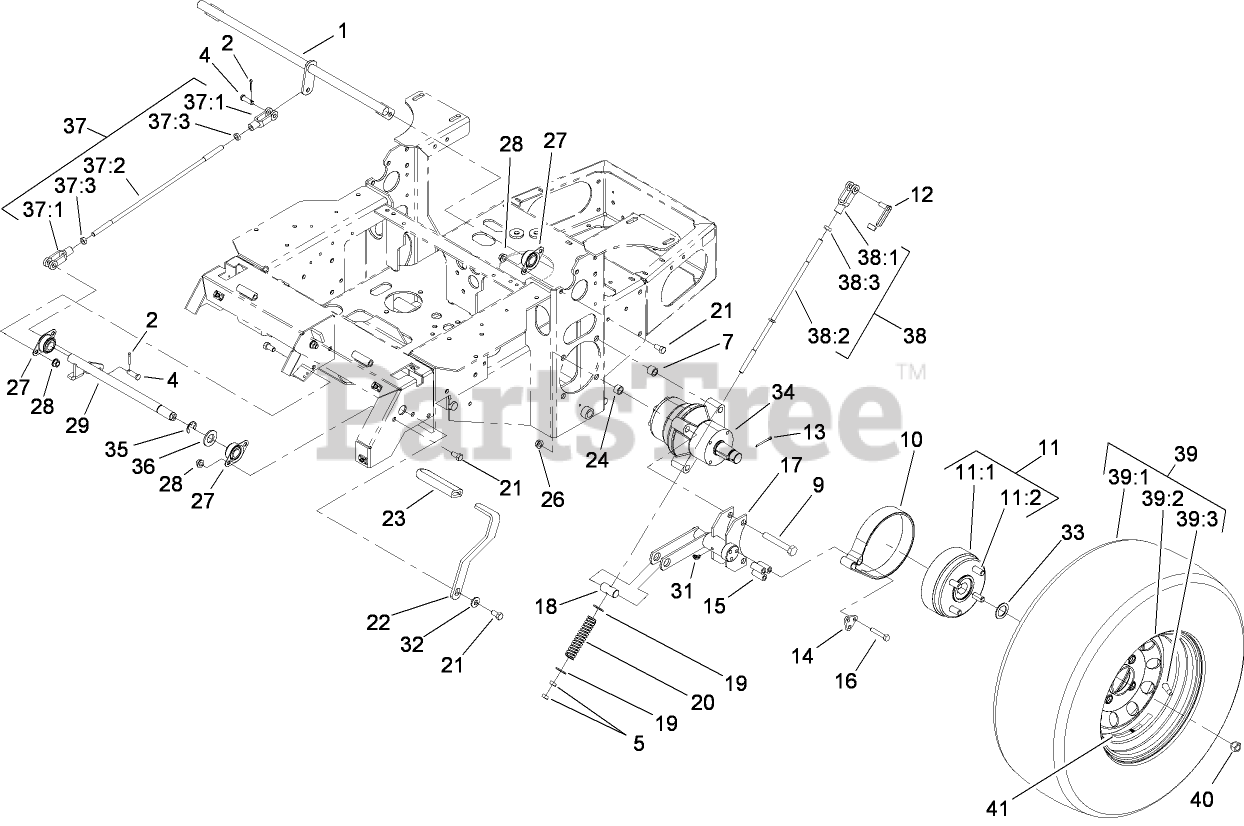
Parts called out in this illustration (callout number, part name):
1	CRANK-BRAKE, PARK
2	PIN-COTTER
4	PIN-CLEVIS
5	NUT-HEX
7	SPACER-WHEEL
9	SCREW-HH
10	BAND-BRAKE
11	HUB AND WHEEL ASM
11:1	HUB-WHEEL
11:2	STUD-WHEEL
12	Pin-Spring, Clevis
13	PIN-COTTER
14	RETAINER-BAND, BRAKE
15	SPACER
16	SCREW-HH
17	BRACKET-BRAKE
18	PIN-TRUNION
19	WASHER-FLAT
20	SPRING-BRAKE
21	SCREW-HH
22	HANDLE-BRAKE, PARK
23	GRIP-LEVER
24	SPACER-WHEEL
26	NUT-HHF
27	BEARING-FLANGE, SIDE
28	NUT-HHF, WHIZ
29	Shaft-Brake, Parking
31	FITTING-GREASE
32	WASHER-BELLEVILLE
33	WASHER-SPACER
34	MOTOR-WHEEL
35	E-RING
36	WASHER-FLAT
37	BRAKE ROD ASM
37:1	YOKE-LINKAGE, BRAKE
37:2	LINKAGE-HANDLE, BRAKE
37:3	NUT-HEX
38	BRAKE ROD ASM
38:1	YOKE-LINKAGE, BRAKE
38:2	ROD-BRAKE
38:3	NUT-HEX
39	WHEEL AND TIRE ASM
39:1	TIRE
39:3	STEM-VALVE
40	NUT-LUG
41	DECAL
